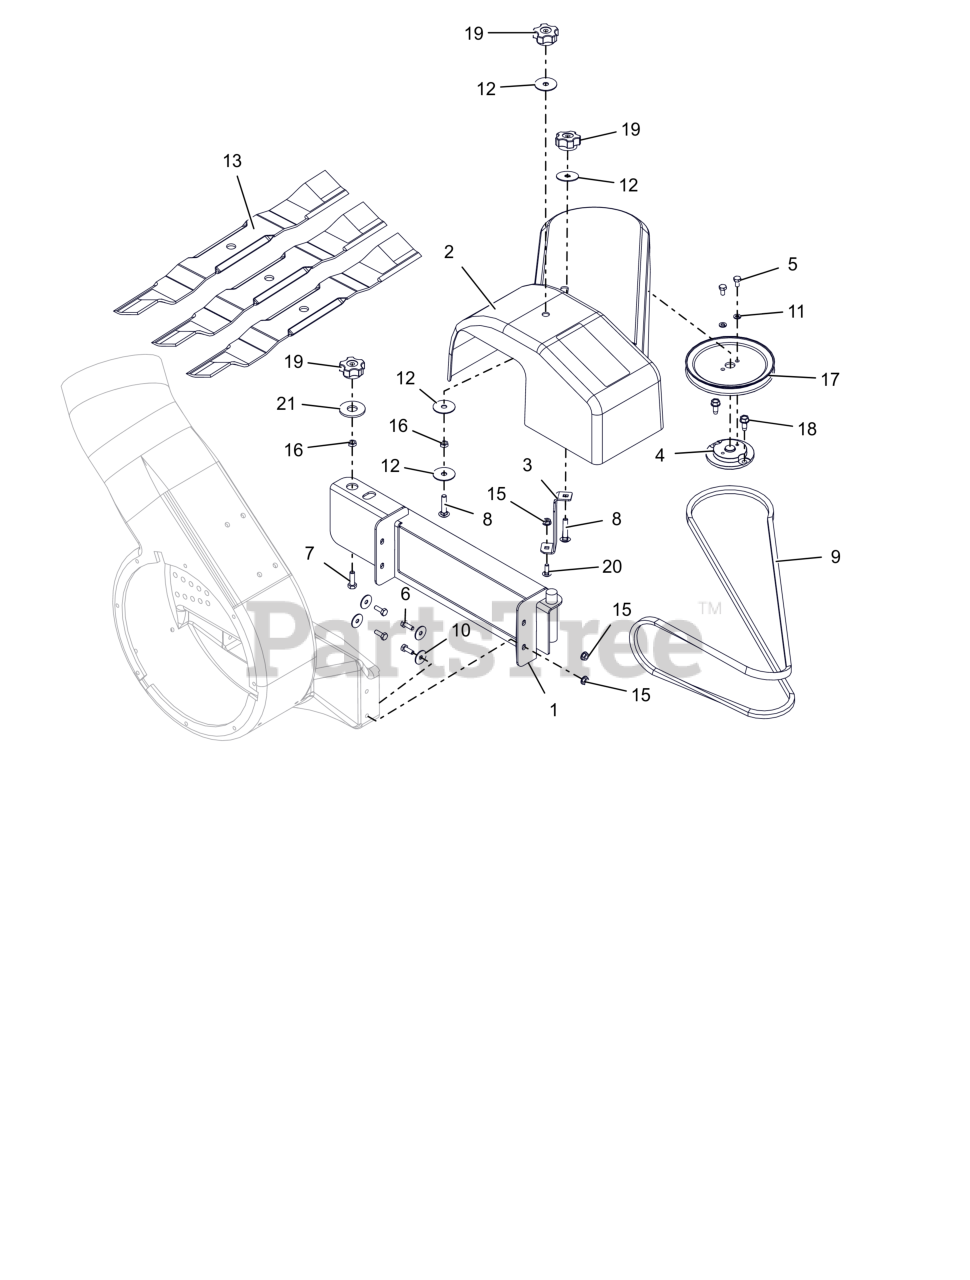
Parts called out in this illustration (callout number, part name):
1	WLDMT, PUMP MOUNTING (BLACK)
2	COVER, BAGGER BELT
3	BRKT, BAGGER BELT COVER
4	ADAPTOR, BAGGER SHEAVE
5	BLT,HEX .25-20X.50 G5 ZCC
6	BLT, HEX .25-20X.75 G5 ZCC
7	BLT, HEX .31-18X1.00 G8 ZCC
8	BLT,RHSN .31-18X1.50 G5 ZCC
9	V-BELT, 4L SECTION - 60" BAG
10	WSHR,FLT .281X1.000X.063 ZCC
11	WSHR,LK-REG .250X.062 ZCC
12	WSHR,FLT .380X1.50X.062 ZCC
13	BLADE, 20.5"- 25 DEG
14	WSHR,FLT .688X1.75X.134 ZCC
15	NUT-LK-TOP-FLG .250-20 GF ZCC
16	NUT-JAM .312-18 G2 ZCC
17	PULLEY, V-6.00 OD X .675 ID
18	SCR,TAP .312-18X.75 HWH TR ZCC
19	KNOB-CLAMPING, .312-18 NYLOC
20	BLT, RHSN .25-20X.750 G5 ZCC
21	WSHR,FLT .438X1.00X.083 ZCC
